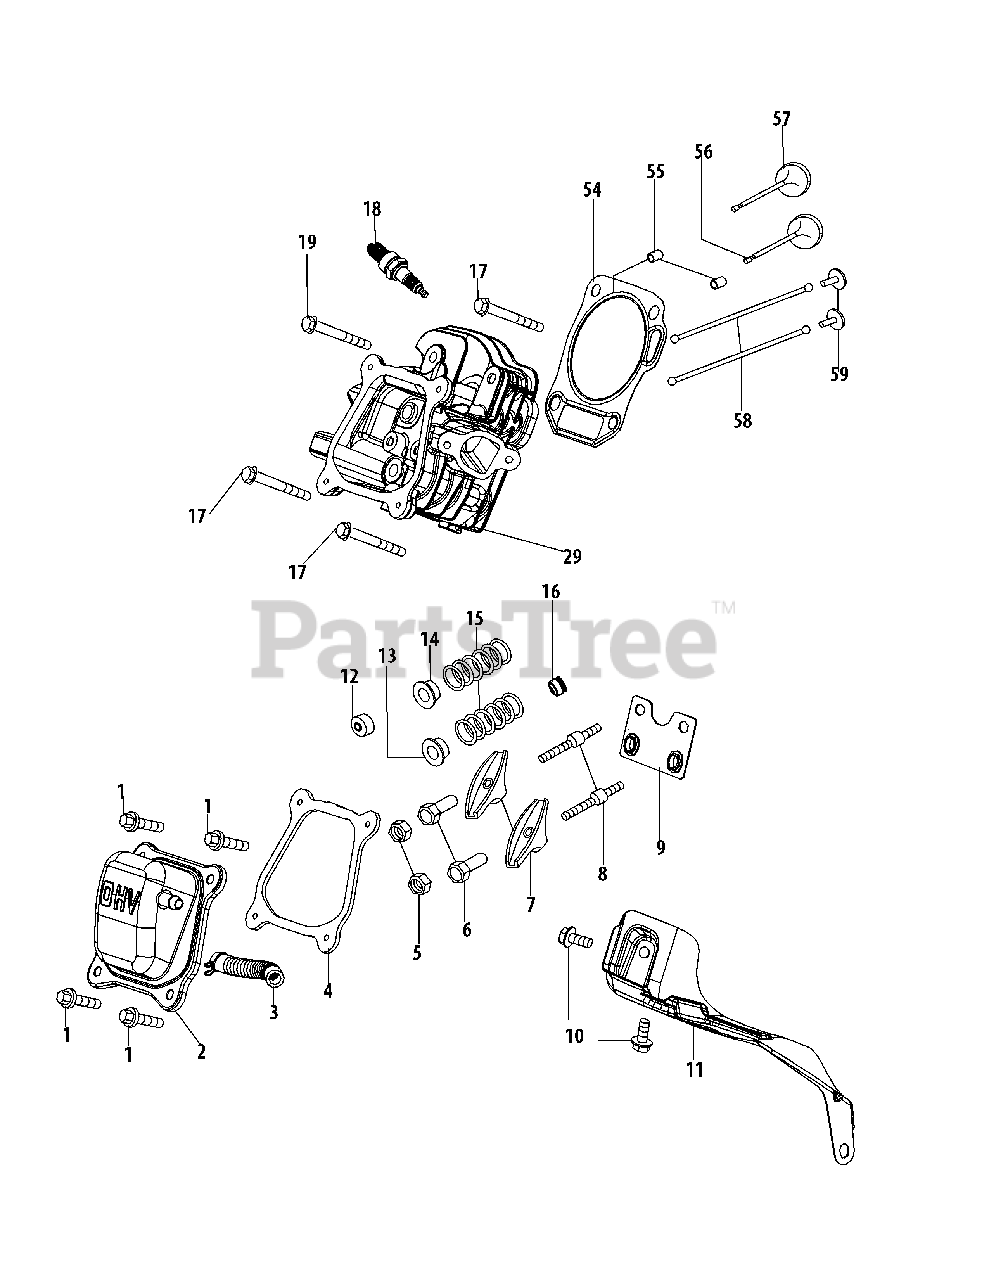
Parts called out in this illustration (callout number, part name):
1	Bolt M6×16
2	Cylinder Head Cover
3	Venting House
4	Gasket, Valve Cover
7	Rocker Arm
8	Rocker Arm Stud
9	Rocker Arm Base
10	Bolt M6×12
12	Rotator,Exhaust Valve
13	Intake Valve Spring Seat
14	Exhaust Valve Spring Seat
15	Spring Valve
16	Oil Seal,Valve
17	Flange Bolt M8×60
18	Spark Plug(F6Rtc)
19	Flange Bolt M8×70
29	Cylinder Head
54	Gasket,Cylinder Head
55	Dowel Pin 10×16
56	Valve Intake
57	Valve Exhaust
58	Push Rod
